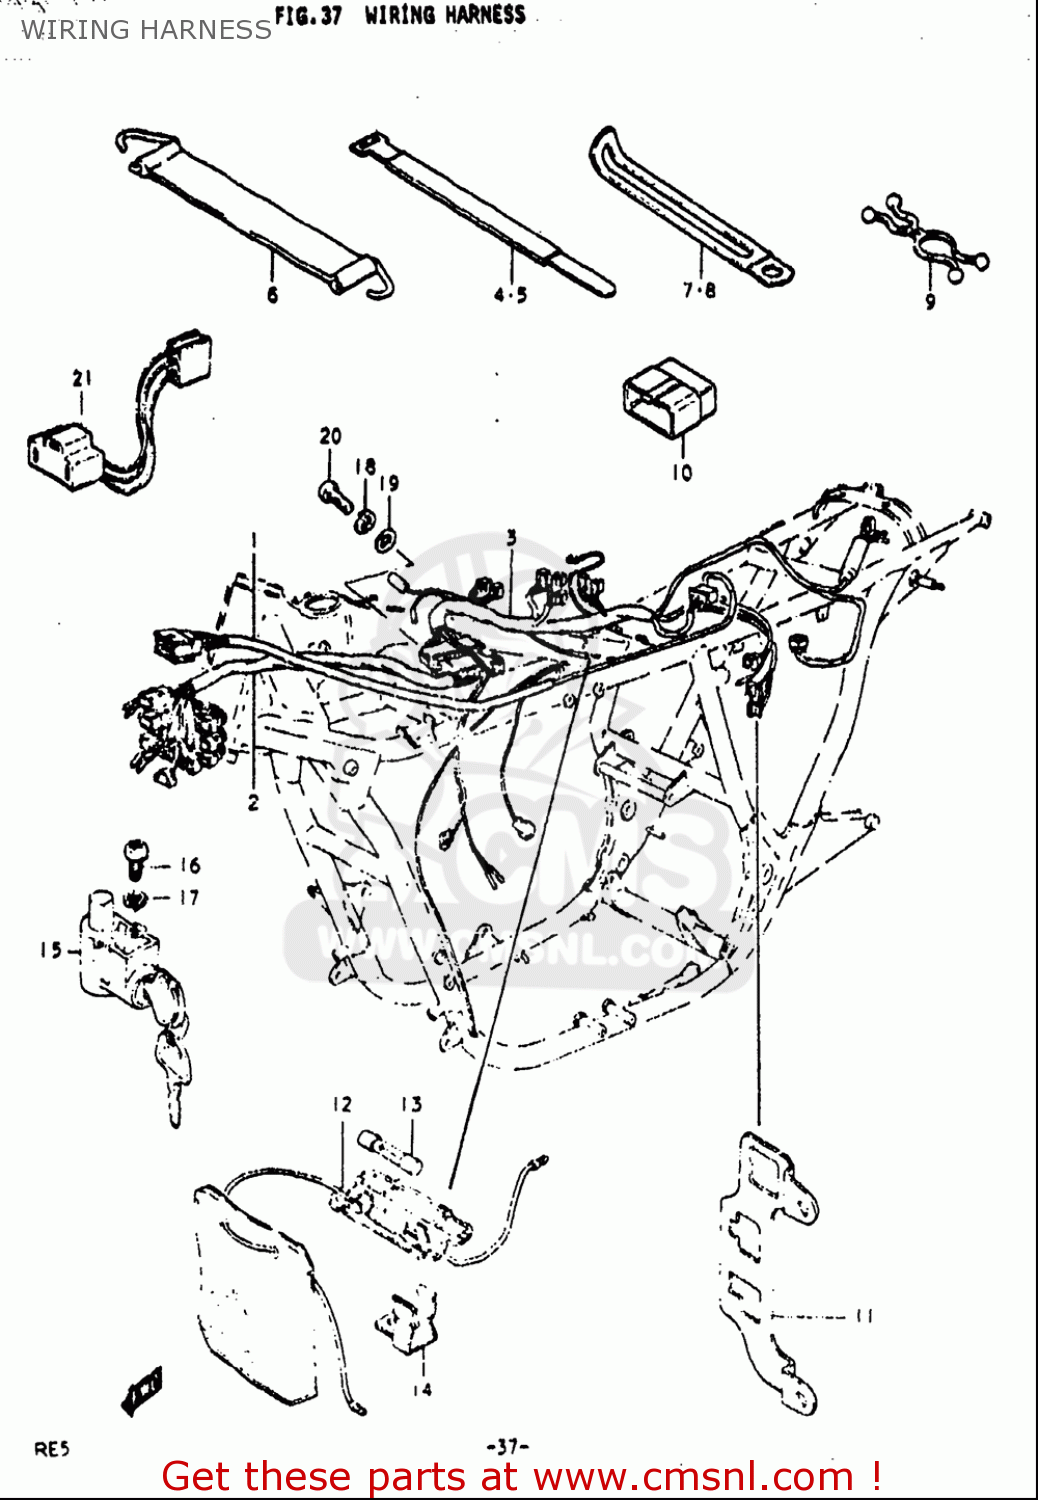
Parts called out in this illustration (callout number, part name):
4	CLAMP
5	CLAMP
7	CLAMP(L:120 T:1.0)
8	CLAMP(L:65)
9	CLAMP
12	CASE ASSY,FUSE
13	FUSE(20A)
15	LOCK ASSY,STEERING
16	SCREW
17	WASHER,LOCK
18	WASHER,LOCK
19	WASHER
20	SCREW
21	LEAD WIRE,HEADLAMP
